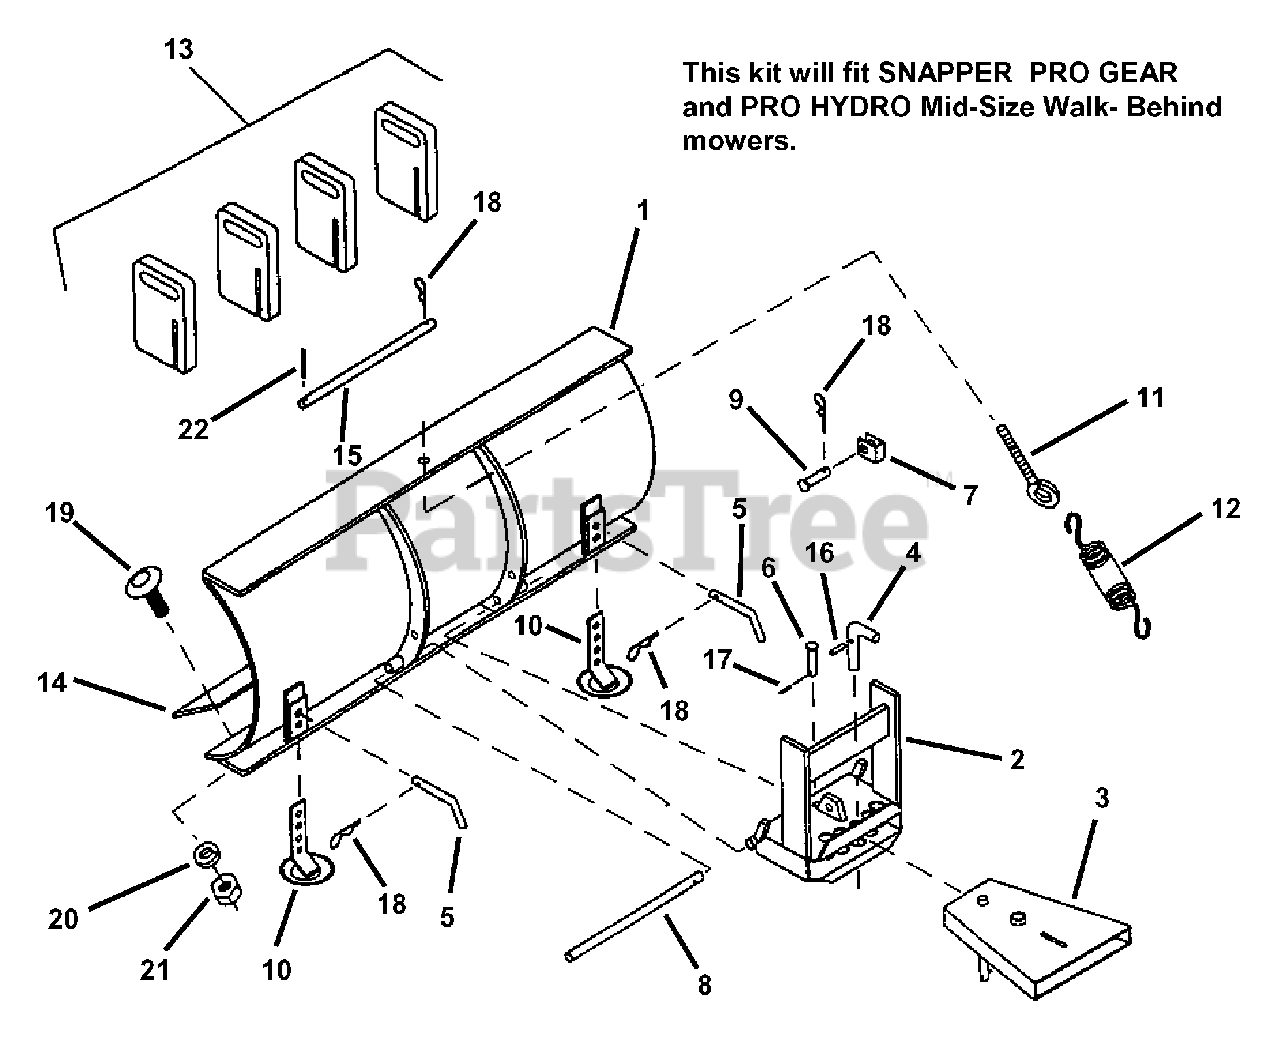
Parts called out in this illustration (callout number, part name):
1	WELDMENT, Blade
2	BOX, Hitch
3	HITCH, Female Quick
4	PIN, Adjustment
5	PIN, Skid Shoe
6	PIN, Pivot
7	LOCK OUT, Trip Spring
8	PIN, 3/4" Dia. x 17-3/4" Long
9	PIN, Trip Spring Lock-Out
10	SKID SHOE
11	EYE BOLT, 5/16-18 x 5" Long w/Hex Nut
12	SPRING
13	COUNTERWEIGHT
14	EDGE, Cutting
15	ROD, Retaining
16	ROLL PIN, 3/16" Dia. x 1" Long
17	ROLL PIN, 1/4" Dia. x 1" Long
19	BOLT, 5/16-18 x 1" Square Neck Carriage
20	WASHER, 5/16" Split Lock
21	NUT 5/16-18 Hex
22	ROLL PIN, 3/16" Dia. x 1-1/2" Long
